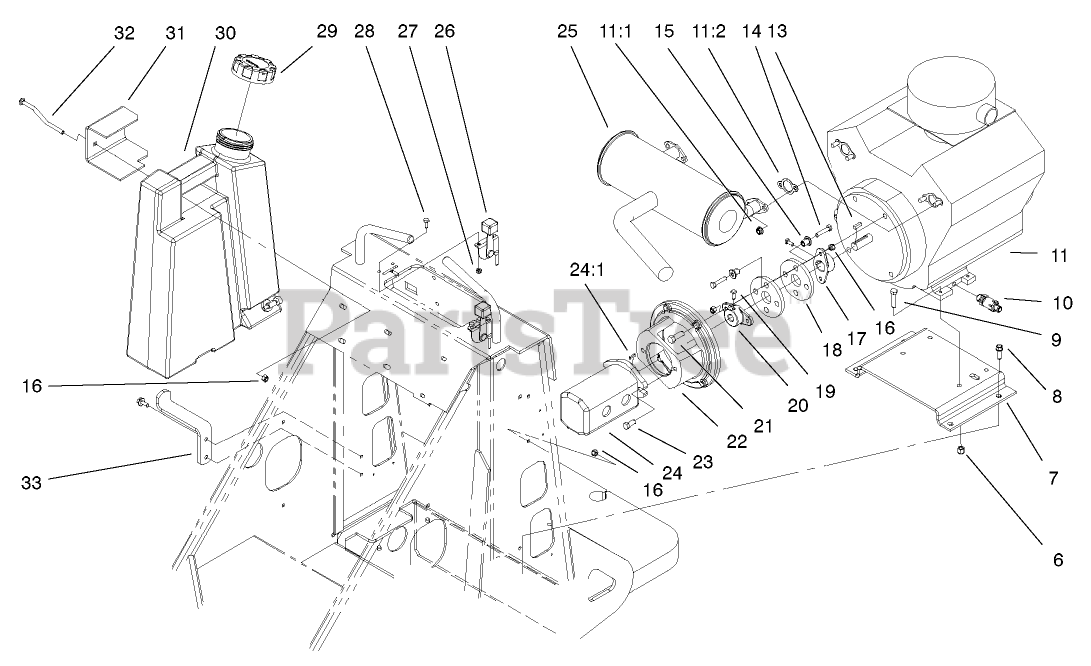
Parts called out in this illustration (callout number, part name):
6	NUT-LOCK, NI
7	Mount-Engine
8	SCREW-TAPTITE
9	SCREW-HH
10	VALVE-DRAIN, OIL
11	Engine (CH22S 66560)Kohler 22 HP
11:1	NUT-HF
11:2	GASKET-EXHAUST
13	KEY-SQUARE
14	SCREW-HH
15	SPACER
16	NUT-LOCK, NI
17	HUB-ENGINE
18	COUPLING-RUBBER
19	SCREW-SQH
20	HUB-PUMP
21	SCREW-HH
22	Mount-Pump
23	SCREW-HHF
24	PUMP-GEAR, TANDEM
24:1	KEY-SQUARE
25	MUFFLER-KOHLER
26	CONTROL-CHOKE / THROTTLE
27	NUT-LOCK, NI
28	SCREW-HHF
29	CAP-FUEL, GAS
30	Fuel Tank ASM
31	Plate
32	BOLT-MOUNT
33	Mount-Tank
